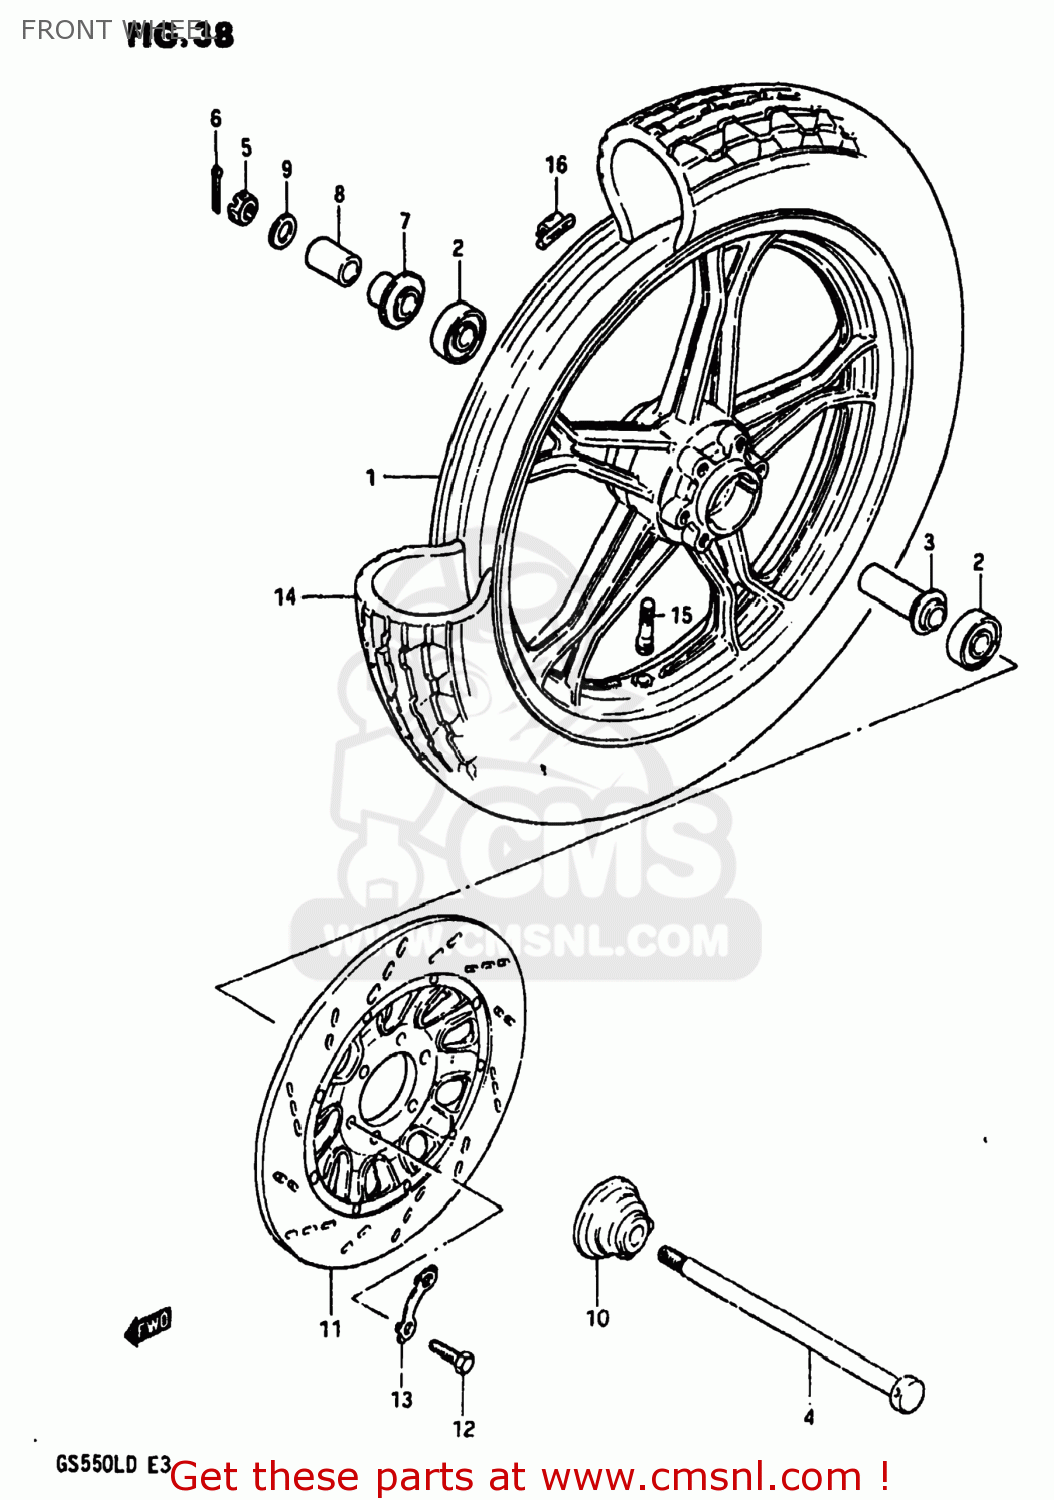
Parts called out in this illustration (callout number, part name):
1	WHEEL, FRONT (2.15X16)
2	BEARING
3	SPACER,FRONT HUB BEARING
4	AXLE,FR
5	NUT 12MM
6	COTTER PIN
7	SPACER,FR HUB BEARING,R
8	SPACER (15X22X32.5)
9	WASHER
10	BOX ASSEMBLY,SPEEDOMETER GEAR
11	DISC,BRAKE
12	BOLT(8X30)
13	WASHER
14	TIRE,FRONT
15	VALVE,TIRE
16	BALANCER,WHEEL
